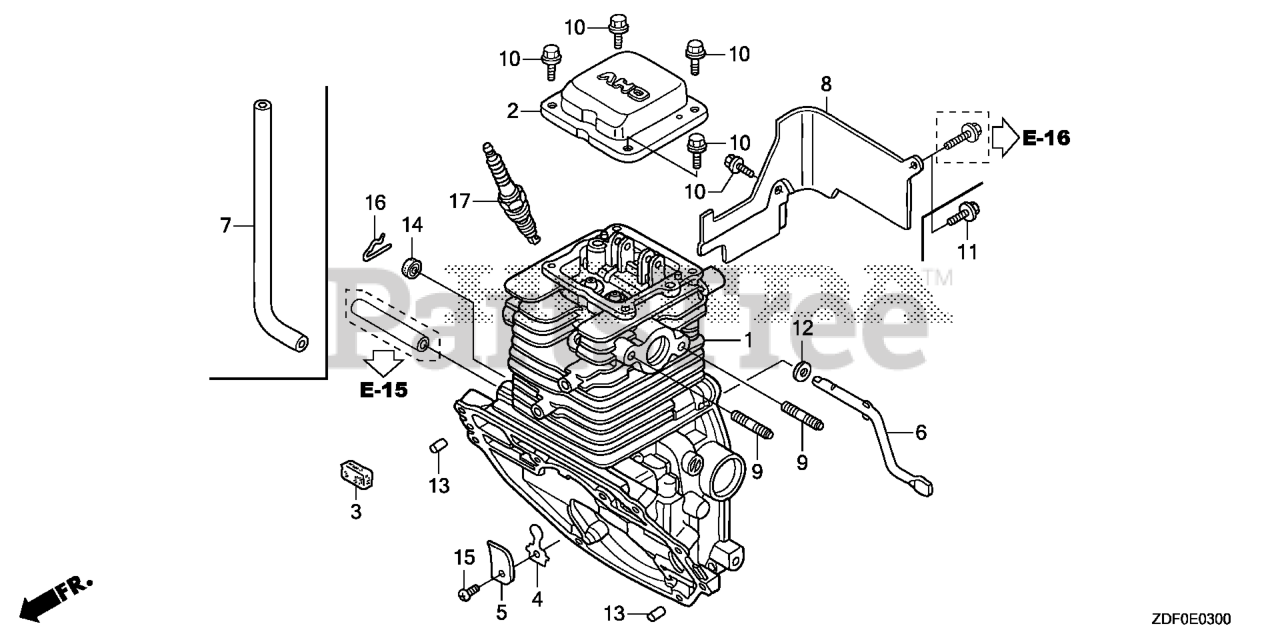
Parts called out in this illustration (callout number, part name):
2	COVER, HEAD
3	FILTER, BREATHER
4	VALVE, OIL OUTLET
5	PLATE, STOPPER
6	SHAFT, GOVERNOR ARM
10	BOLT, FLANGE (5X12)
12	WASHER (5.2X9)
13	ROLLER (6X14.8)
14	OIL SEAL (5X11X5)
15	SCREW, PAN (3X5)
16	PIN, LOCK (6MM)
17	SPARK PLUG (U14FSR-UB) (DENSO)
17	SPARK PLUG (CR4HSB) (NGK)
17	SPARK PLUG (U16FSR-UB) (DENSO)
17	SPARK PLUG (CR5HSB)
